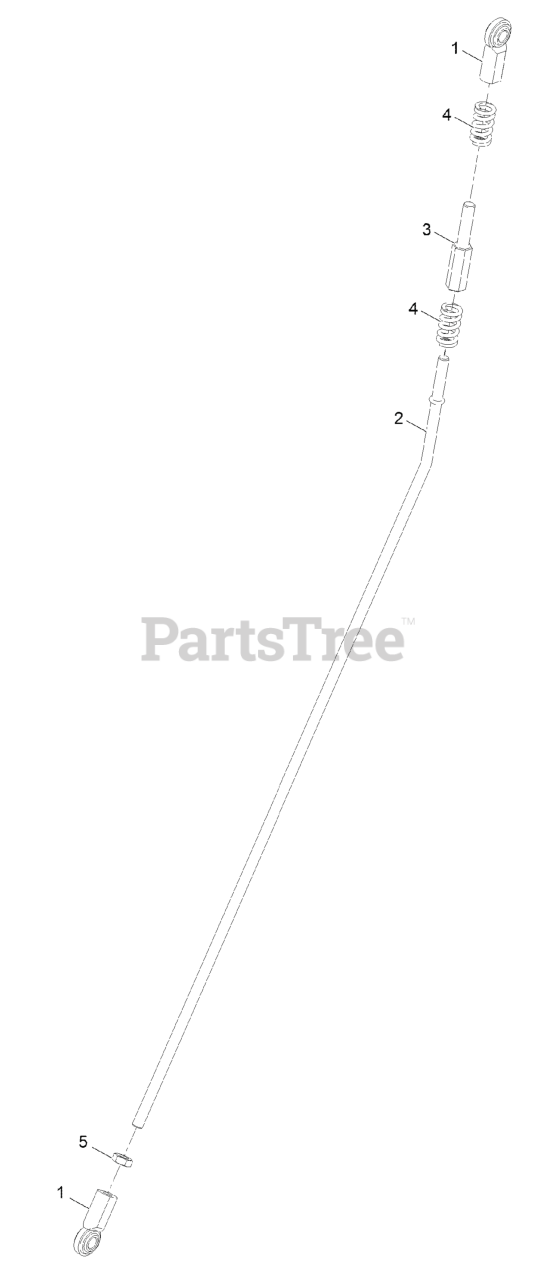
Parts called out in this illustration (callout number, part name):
1	JOINT-BALL, END
2	LINKAGE-MOTION
3	ROD-ADJUSTMENT
4	SPRING, COMPRESSION
5	NUT-HJ
